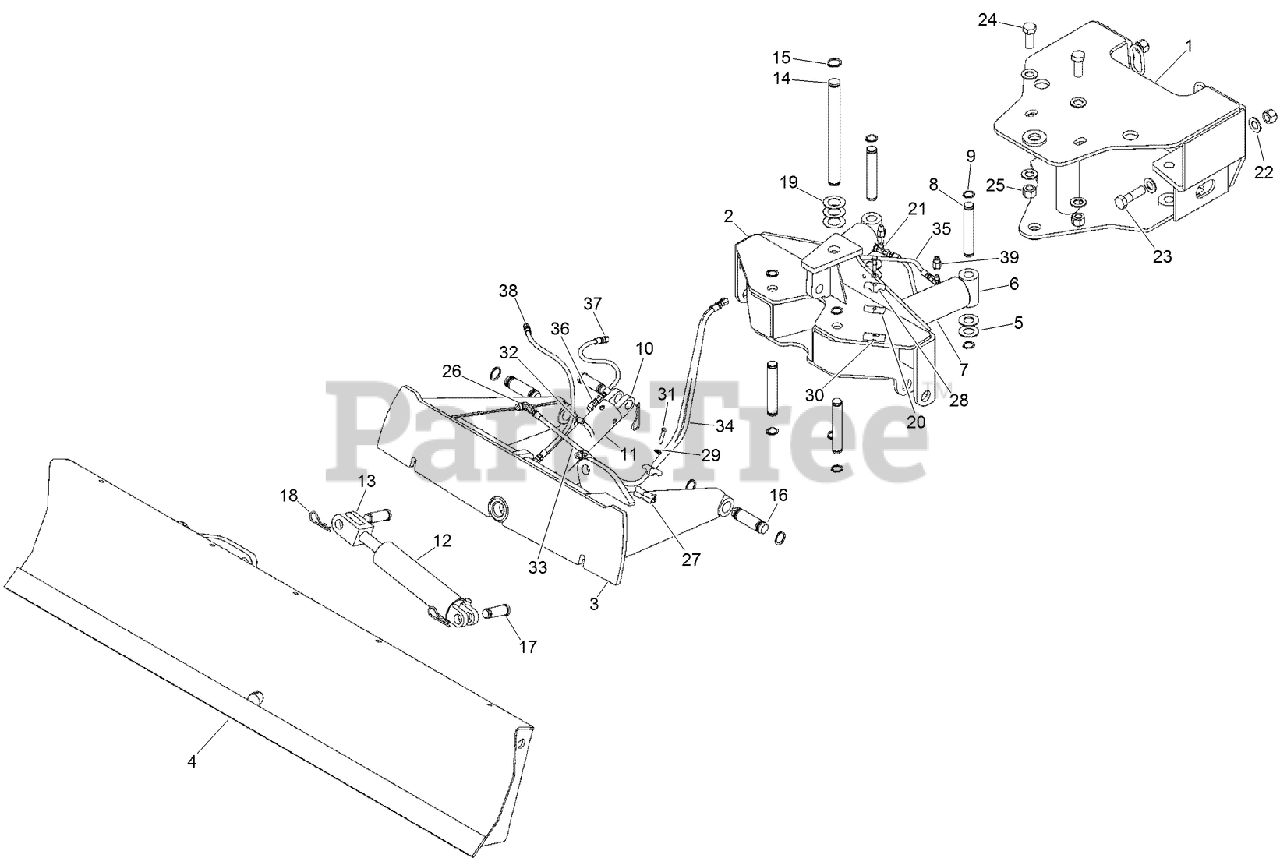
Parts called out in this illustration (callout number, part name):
1	WELDMENT, FRAME - Backfill Mtg
2	WELDMENT, PIVOT - Backfill
3	WELDMENT, ARM - Backfill
4	WELDMENT, BLADE - Backfill
5	WASHER-FLAT
6	CYLINDER - Barrel
7	CYLINDER - Barrel
8	PIN-ANGLE, CYLINDER
9	RING-RETAINING
10	CYLINDER - Hydraulic, Barrel
11	CYLINDER - Hydraulic, Barrel
12	CYLINDER - Hydraulic, Barrel
13	CYLINDER - Hydraulic, Barrel
14	PIN-BLADE
16	PIN-BLADE
17	PIN-CLEVIS
18	PIN-COTTER, QUICK ATTACH
20	CONNECTOR-Str Thd 3/8, 37FL-ORB 3/8
21	FITTING-TEE
23	SCREW-CAP, HH
26	ELBOW-90 Adj 37FL, 3/8 x 1/2 Tube
27	RETAINER - Hose
28	CLAMP-TUBE
29	WASHER-FLAT
30	NUT-SQUARE
31	BOLT-Hex Hd .375 x 1.75 GR5 ZND
32	CLAMP - Hose Type F #52
33	HOSE - Hydraulic, Back Fill Blade Tilt
34	HOSE - Hydraulic, Back Fill Blade Tilt
35	HOSE, Hyd, C2 tee at diff lock valve (branch) to front axle diff lock
36	ORIFICE - 0.062 - Inline
37	HOSE, Hyd, C2 tee at diff lock valve (branch) to front axle diff lock
38	HOSE-Trencher Lift
39	ADAPTER - Tube IPC, 37FL, 3/8 x 1/2
